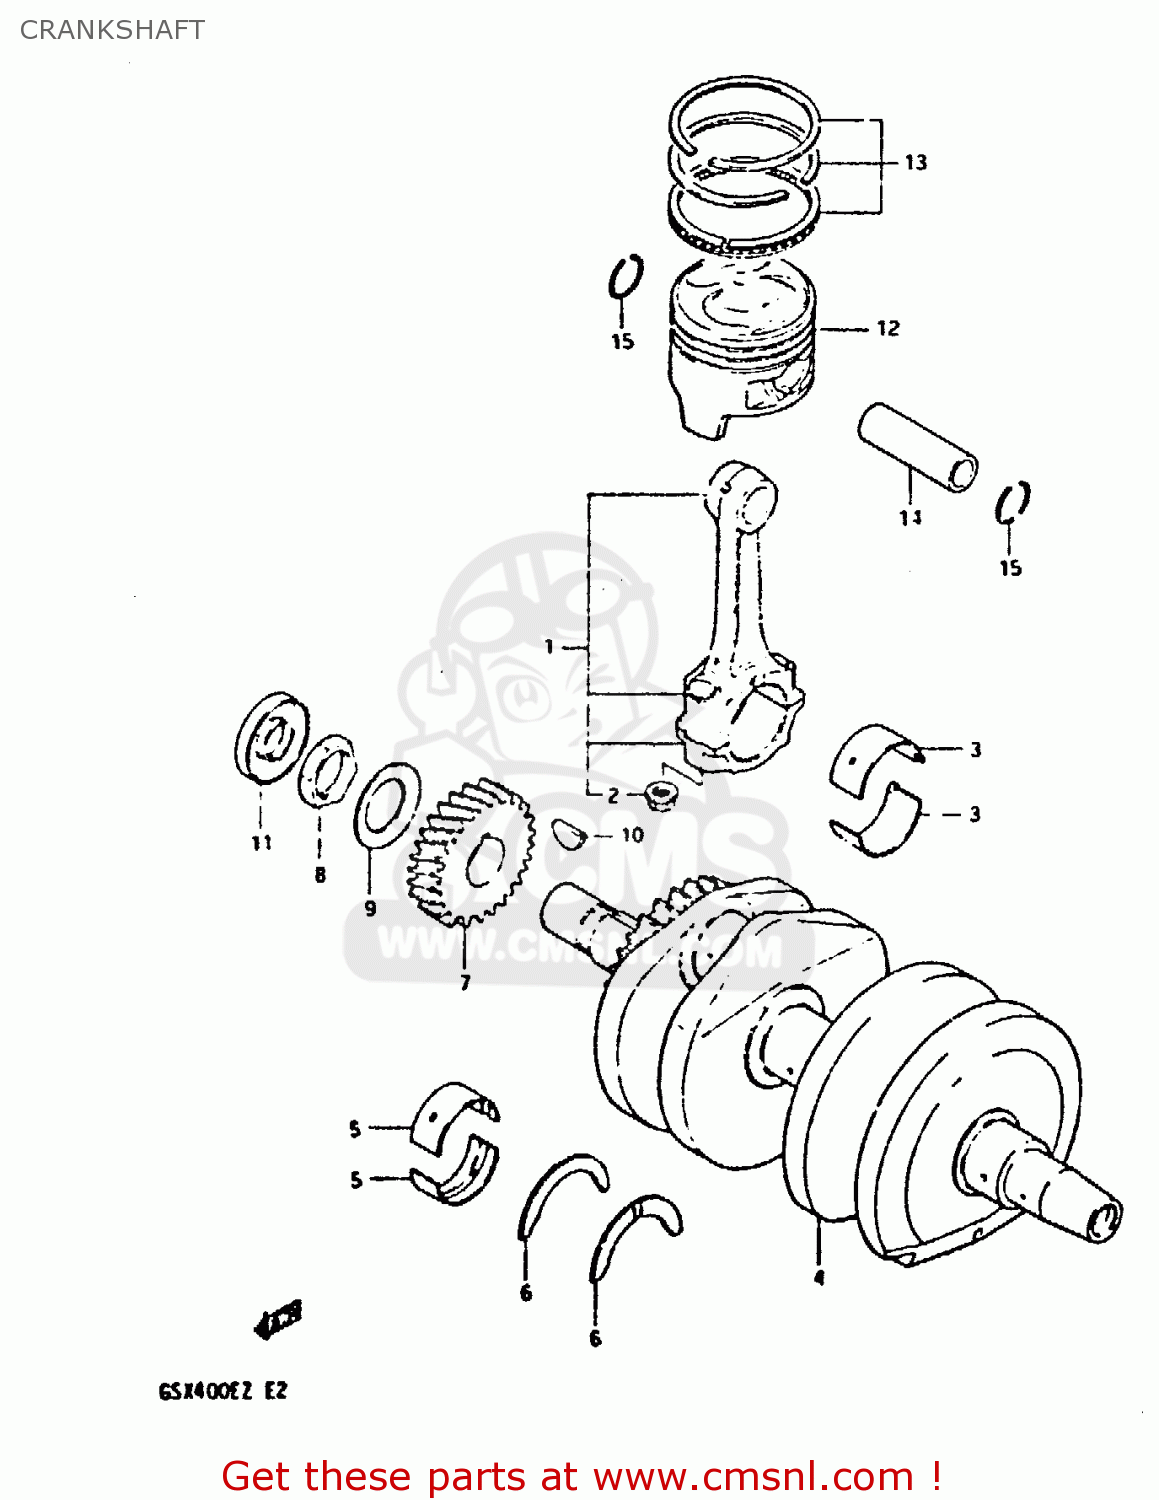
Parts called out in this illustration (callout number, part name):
1	ROD ASSEMBLY,CONNECTING
2	NUT
3	BEARING,CRANK PIN
4	CRANKSHAFT
5	METAL CRANKSHAFT
6	BEARING,CRANK THRUST
7	GEAR,PRIMARY DRIVE NO.28
8	NUT
9	WASHER
10	KEY
11	OIL SEAL
12	PISTON (STD)
13	RING SET,PISTON
14	PIN,PISTON
15	CIRCLIP,PISTON PIN
